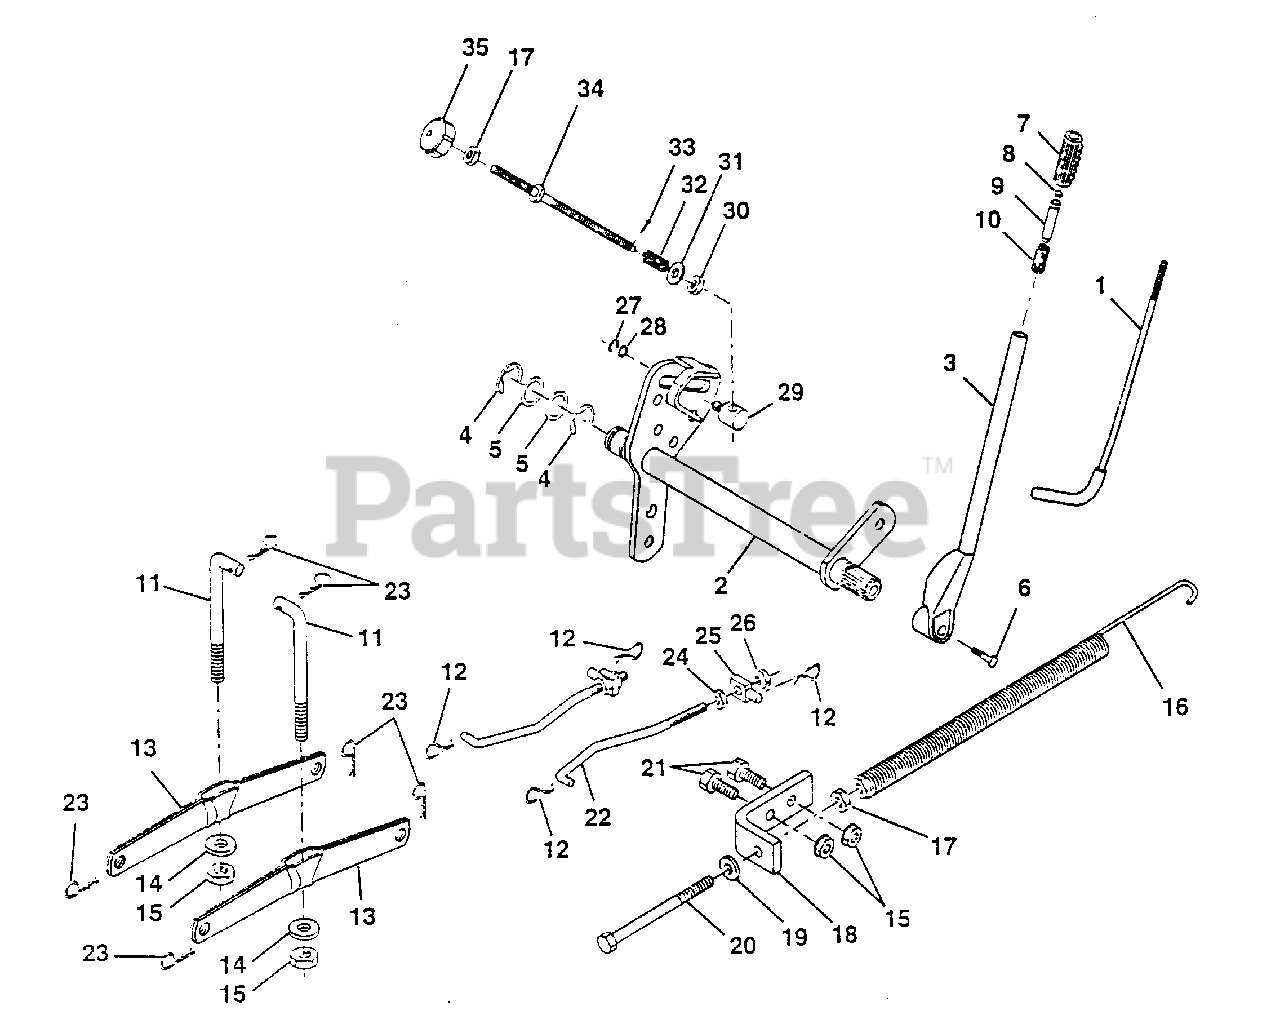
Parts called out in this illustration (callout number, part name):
1	Rod Asm., Lever
2	Shaft Asm., Lift Vgt
3	Lever Asm., Lift Rh
4	E-Ring Truarc #5133-87
5	Washer 29/32 x 1-1/4 x 16 Ga.
6	Bolt, Fin Hex 3/8-16 x 1-1/2
7	Grip, Handle Bicycle
8	Button, Plunger
9	Plunger, Lever Lift
10	Spring 2-1/8"
11	Link Lift
12	Retainer, Spring
13	Arm, Suspension Vgt
14	Bearing
15	Nut, Lock Hex W/Wsh 3/8-16 Unc
16	Spring Asm., Assist Lift
17	Nut, Hex Jam 3/8-16 Unc
18	Bracket, Spring Assist
19	Washer 13/32 x 13/16 x 16 Ga.
20	Bolt, Adjust Spring Assist
21	Bolt, Fin Hex 3/8-16 x 1
23	Retainer, Spring
24	Nut, Jam Hex 1/2-13 Unc
25	Trunnion
26	Nut, Lock W/Wsh 1/2-13 Unc
27	Ring, Klip #T5304-37
28	Washer 15/32 x 3/4 x 16 Ga.
29	Trunnion, Dp Stop Dbl Thds Plt
31	Washer 13/32 x 5/8 x 16 Ga.
32	Spring, Compression Inf Hgt
33	Pin, Cotter 3/32 x 1/2
34	Rod, Adj Lift
35	Knob, Inf 3/8-16 Unc
